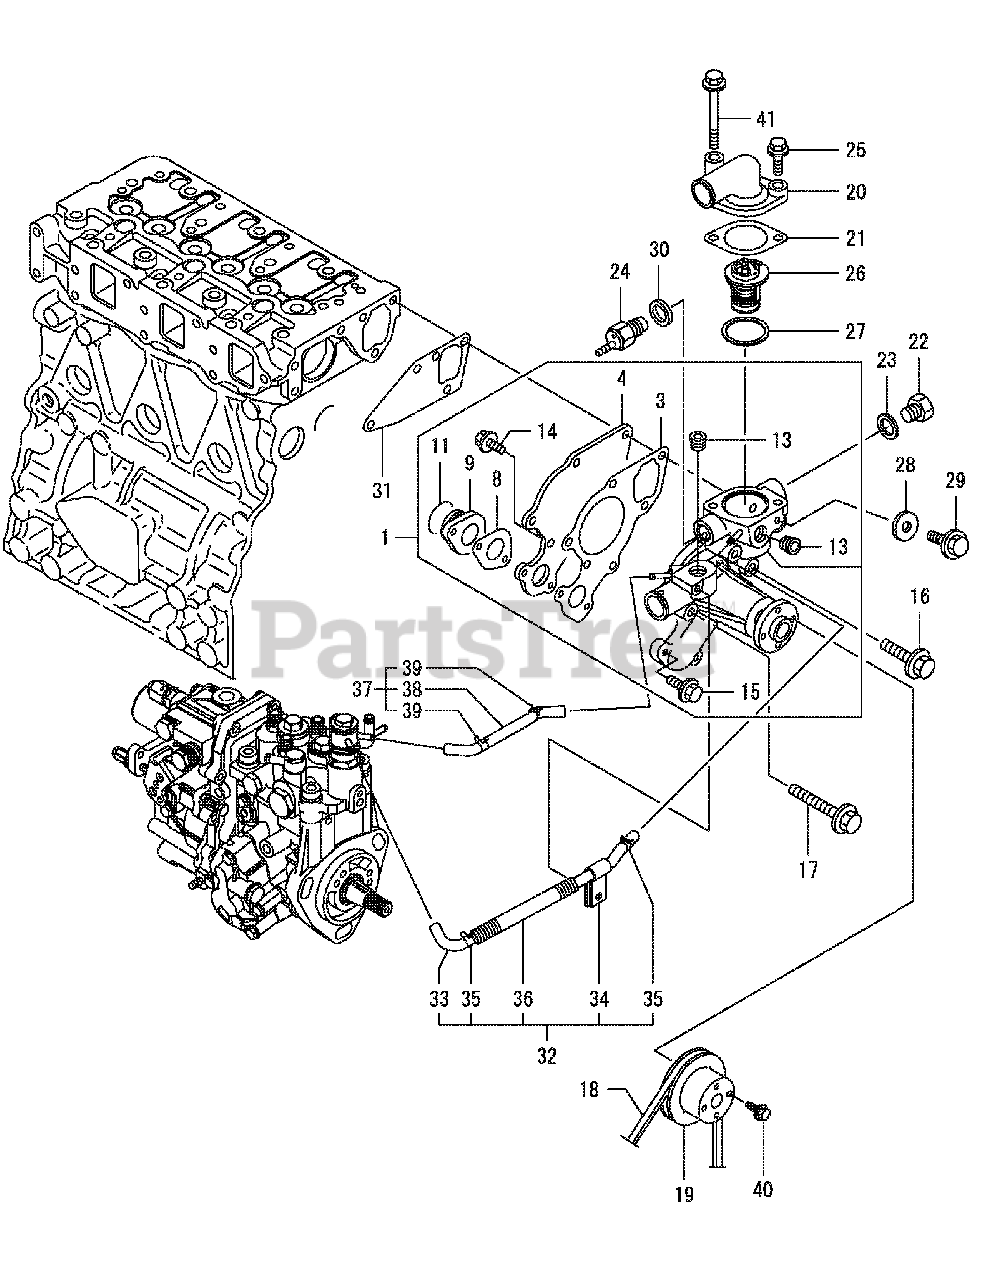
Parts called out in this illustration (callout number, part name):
1	Water Pump Assembly
3	Water Pump Gasket
8	Water Pump Gasket
13	Screw Plug, PT 3.8
20	Thermostat Cover
24	Thermostat Switch
27	Thermostat Gasket
28	Round Gasket, 8
31	Water Pump Gasket
32	Water Pipe, MP2 A
33	Water Pipe, MP2 A
36	Corrugated Tube
37	Water Pipe, MP2 B
38	Water Pipe, MP2 B
